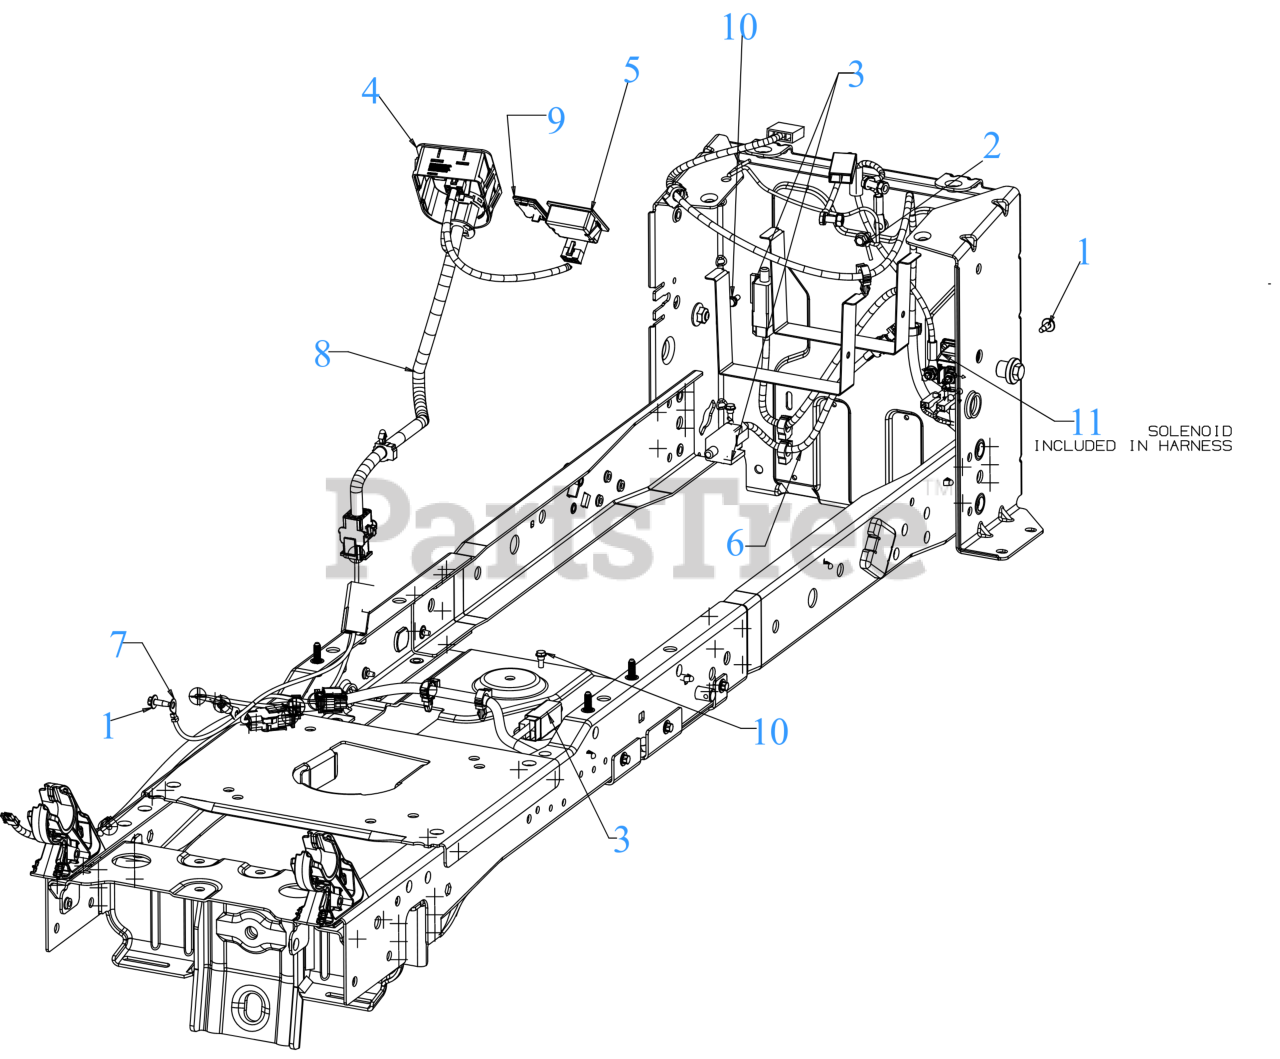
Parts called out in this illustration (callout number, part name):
1	SCREW M6-1 x .625
2	SCREW 1/4-20X.625
3	INTERLOCK SWITCH (NO/NC)
4	IGNITION MODULE SWITCH RMC (MAN PTO BLK)
5	HOUR METER/SERVICE MINDER
5	Cub Cadet HOUR METER KIT
5	Troy-Bilt HOUR METER KIT
6	REVERSE HARNESS
7	JUMPER HARNESS (E GOV)
8	HARNESS (MPTO/RMC/HRMTR/DC)
10	SHOULDER SCREW
11	12V SOLENOID
